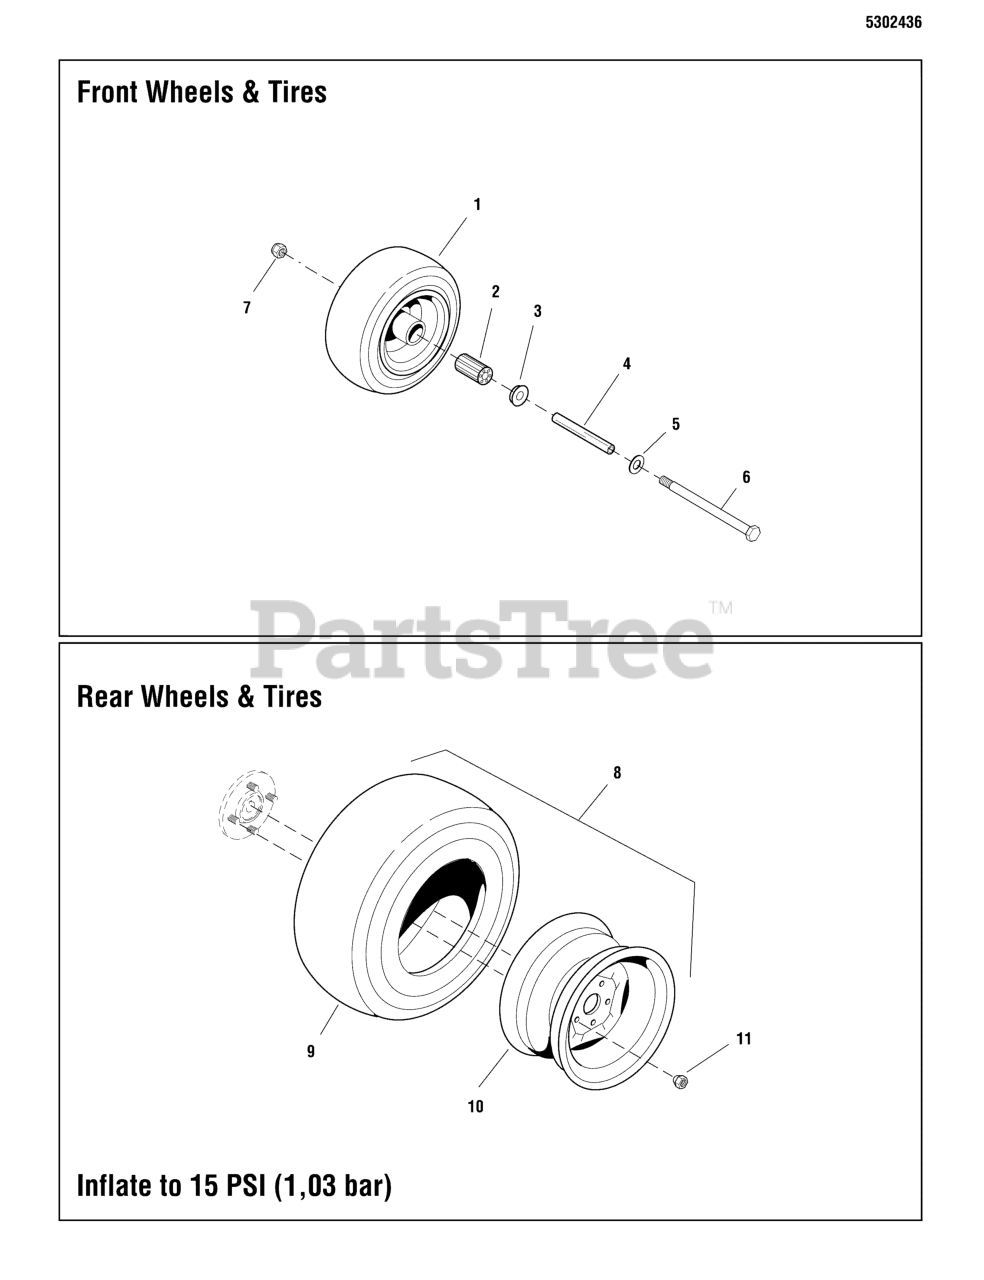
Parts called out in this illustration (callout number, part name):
1	TIRE ASSM, 11X4.00-5 FLAT FREE
2	BEARING, CASTER WHEEL
3	RETAINER, BEARING
4	CASTER AXLE DDSH
5	WASHER, 1/2 SAE
6	BOLT, 1/2-13 X 7 GD5 YZ
7	NUT, Hex Flange, Nylock, 1/2-13
8	TIRE ASM, 20X7-10, 2.0 OS TURF MASTER
9	TIRE, 20 X 7 -10 NHS, TURF MASTER
10	WHEEL, 10X6, 4 BOLT, NEG .700" OFFSET
11	NUT, 1/2-20, FOR WHEEL BOLT SILVER
